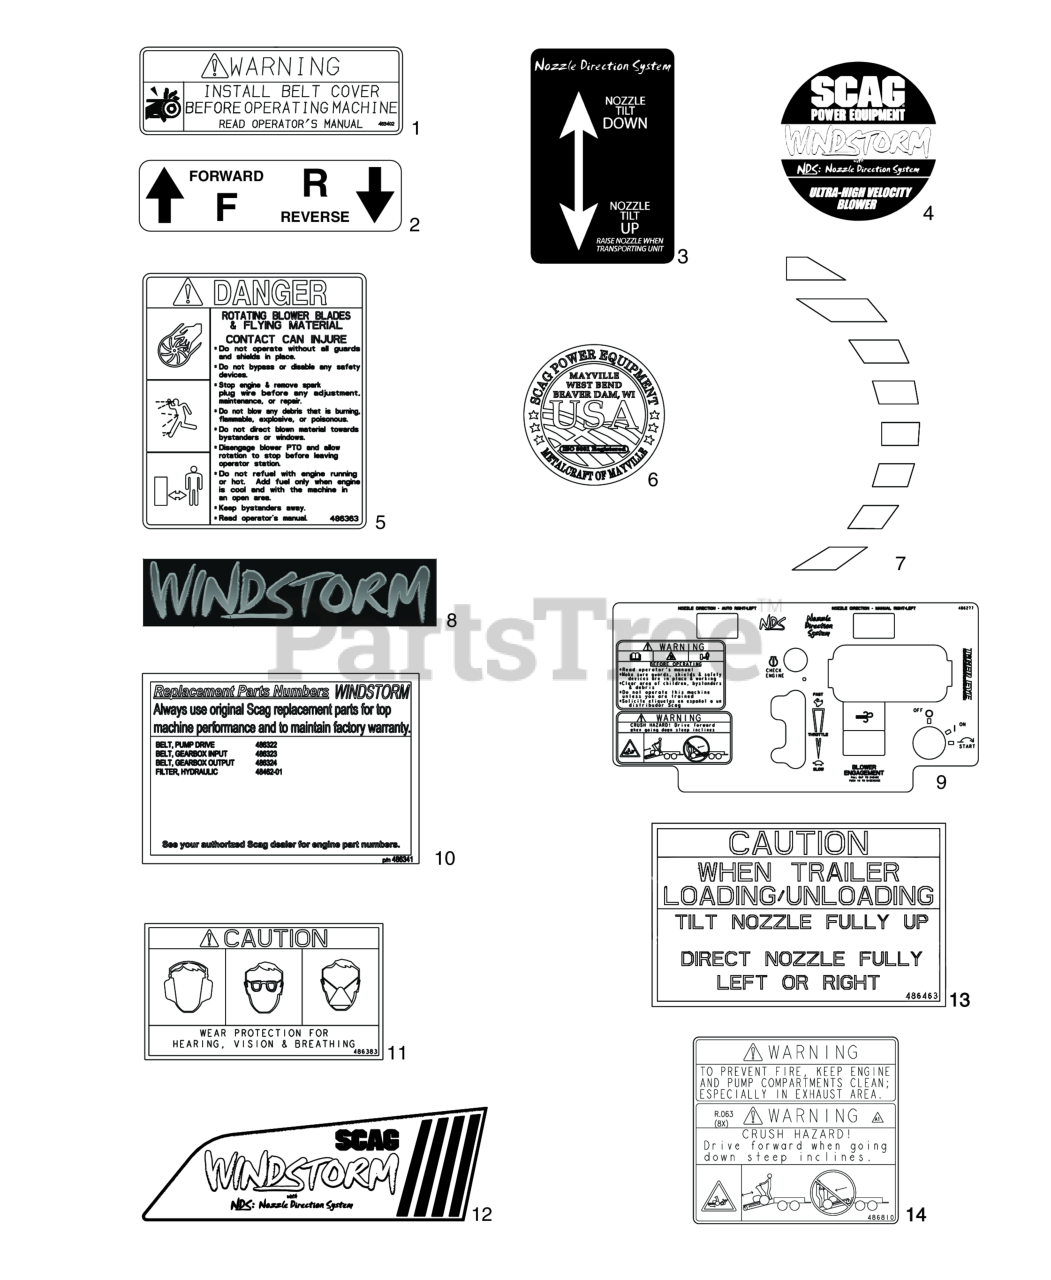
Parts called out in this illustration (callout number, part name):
1	Decal, Warning - Belt Cover
2	Decal, Traction Control
3	Decal, Nozzle Tilt
4	Decal, Front-Windstorm
5	Decal, Danger-Blower
6	Decal, Metalcraft - USA
7	Decal, Housing-Front
8	Decal, Housing-Side
9	Decal, Instrument Panel
10	Decal, Windstorm Replacement Parts
11	Decal, Personal Protection
12	Decal, Windstorm Tank
13	Decal, Trailer Loading
14	Decal, Burn Hazard
